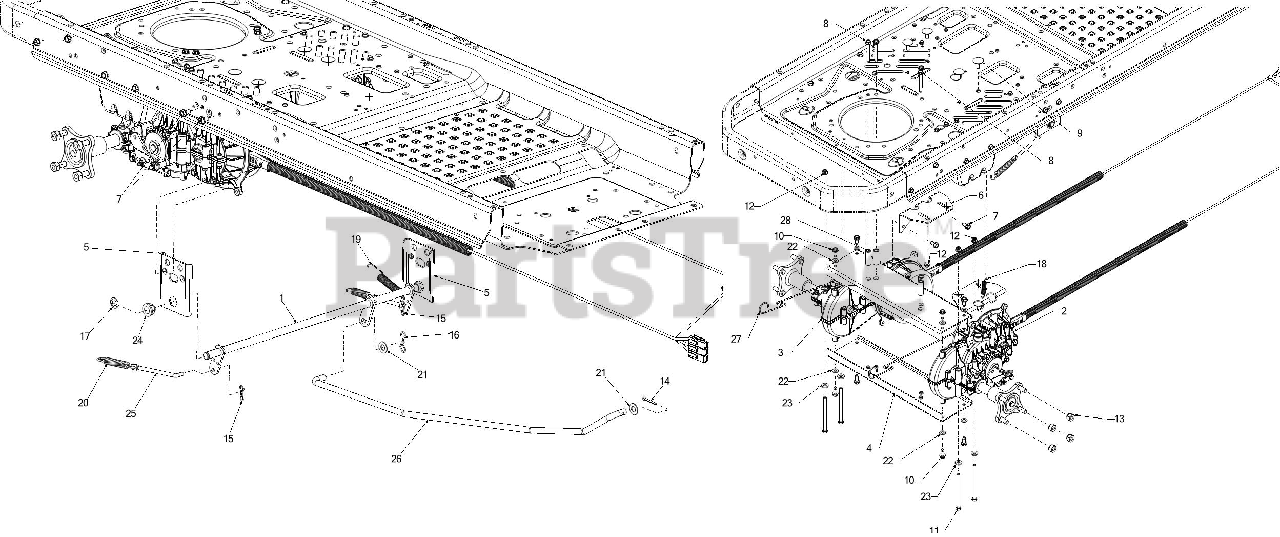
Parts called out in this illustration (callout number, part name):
1	BRAKE SHAFT ASSEMBLY
2	TRANSMISSION ASSEMBLY (RH)
3	TRANSMISSION ASSEMBLY (LH)
4	AXLE MOUTING BRACKET
5	BRAKE SHAFT BRACKET
6	MOTOR TORQ BRACKET
7	SCREW 5/16-18 x .750
8	SCREW-5/16-18 x 2.5
9	SCREW 5/16-18 x 1.00
10	SCREW 5/16-18 x .750
11	SCREW 5/16-18 x 4.5 GR5
12	FLANGE LOCK NUT 5/16-18
13	LUG NUT 7/16-14
14	COTTER PIN-5/32 DIA
15	BOW TIE COTTER PIN 1/4-5/16
16	BOW TIE COTTER PIN
18	EXTENSION SPRING
19	EXTENSION SPRING .63 x 4.95
20	EXTENSION SPRING
21	FLAT WASHER .510 x 1.00 x .060
22	FLAT WASHER
23	FLAT WASHER
24	FLANGE BEARING
25	DROP AXLE BRAKE ROD
26	FRONT BRAKE ROD
27	DROP AXLE DUMP ROD
28	SPACER .345X.625X1.798 E
